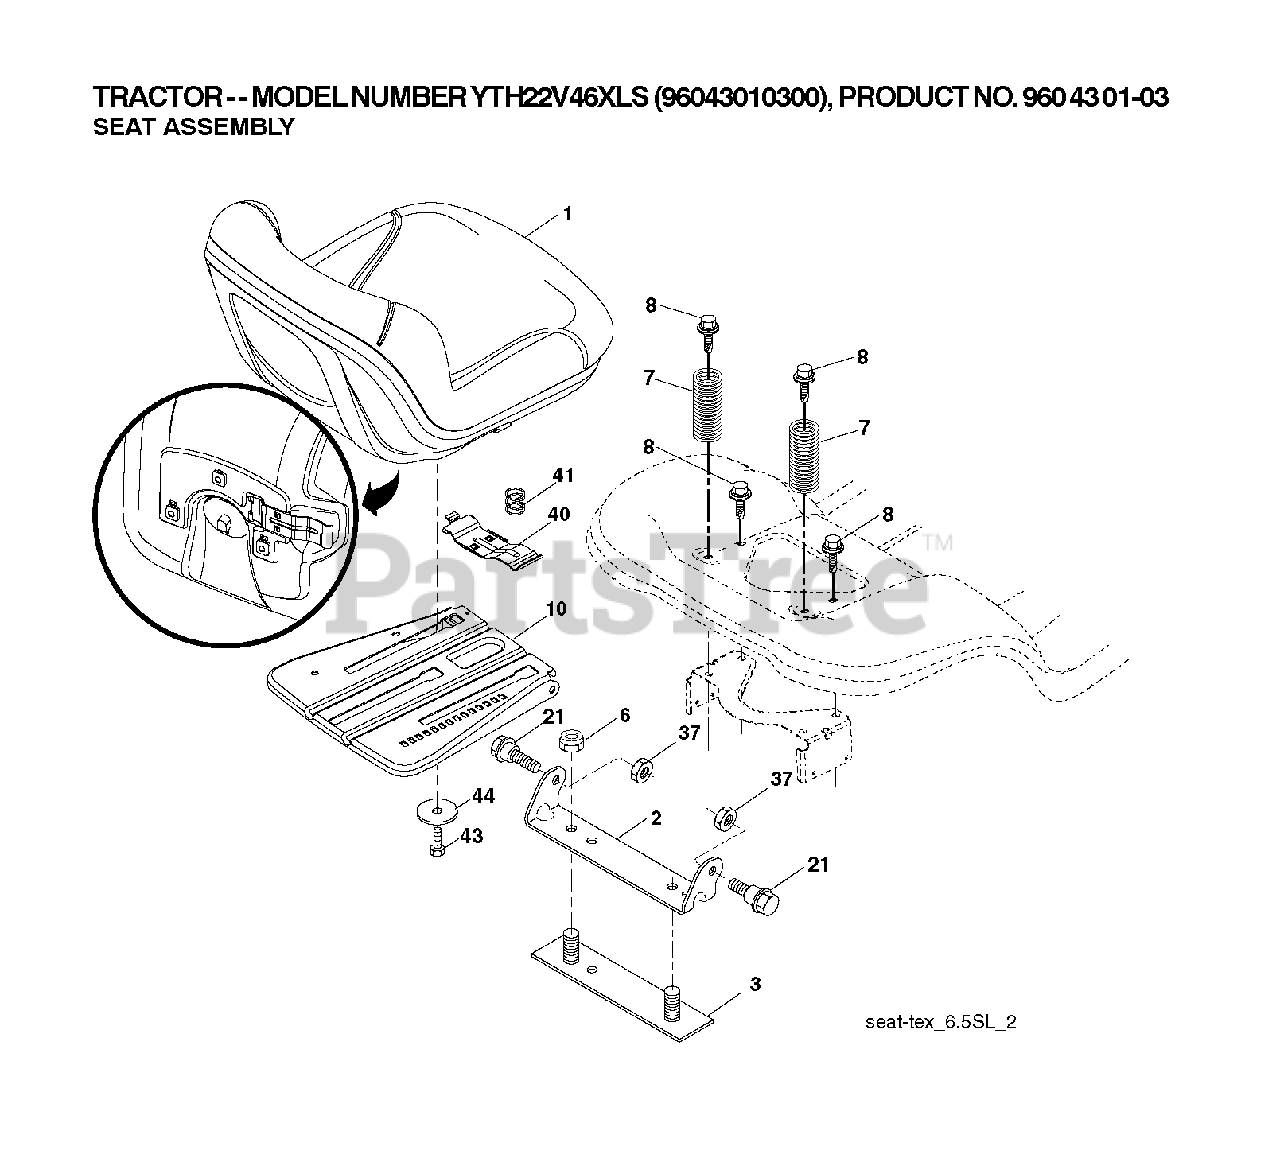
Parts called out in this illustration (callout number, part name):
1	SEAT.TH151.GREY.PREM.HUSQ.MI
2	BRKT.PIVOT.FENDER
3	STRAP
6	NUT
7	SPRING COMPRESSION
8	BOLT, 5/16-18 X 1 3/4
10	PAN.ASM.SEAT.3PT
21	BOLT.SHOULDER.5/16-18
37	NUT.71038.31-18.HEX.NYLOCK
40	HANDLE.SLIDE.SEAT.TEX.GREY
41	SPRING.LATCH.SEAT.TEX
44	WASHER 13/32 X 2-3/8 X 12GA
